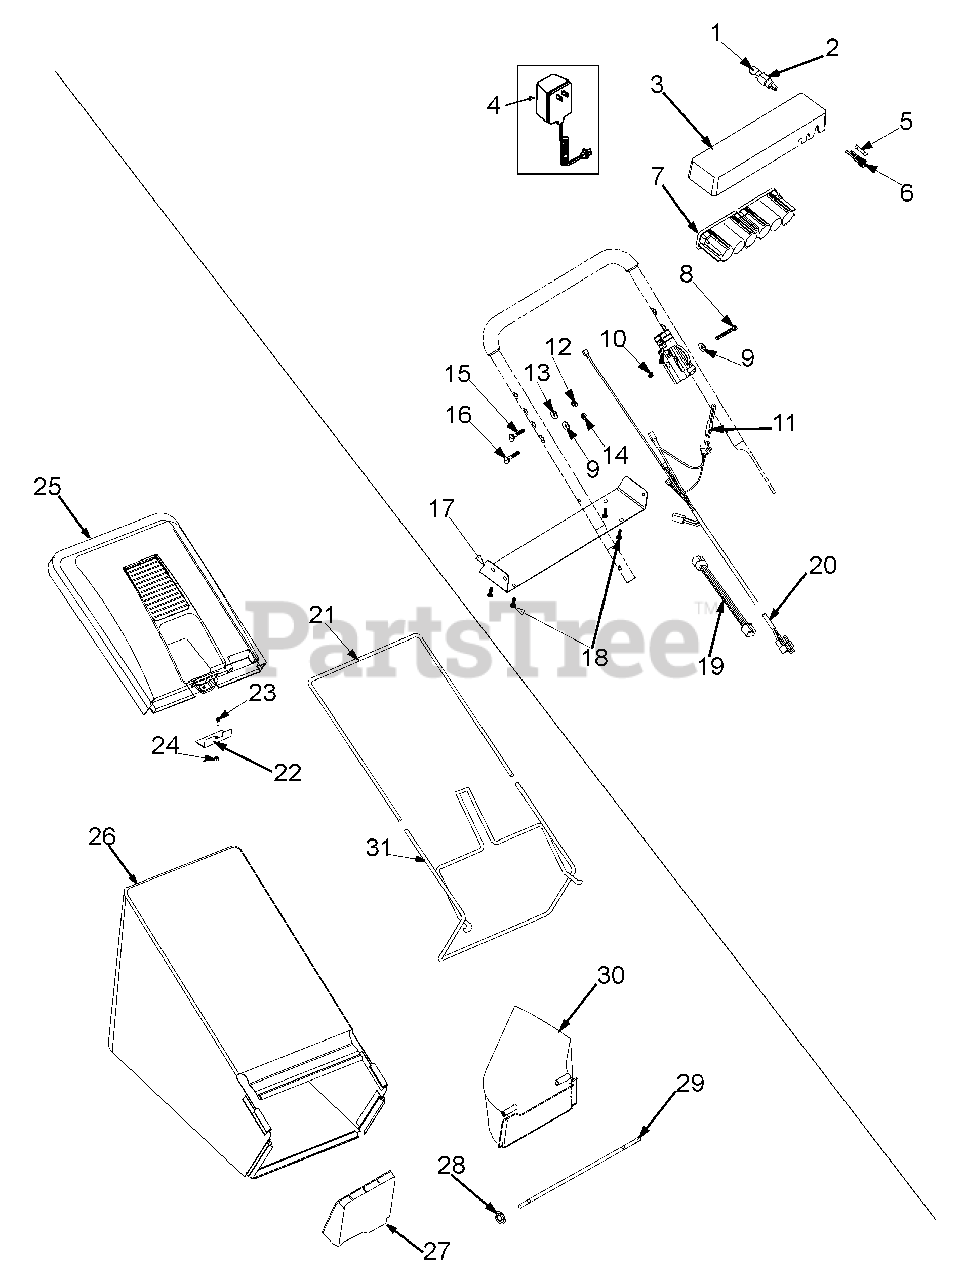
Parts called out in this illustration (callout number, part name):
1	Ignition Key
2	Key Switch
3	Battery Tray
4	Battery Charger
5	Fuse 7.5 Amp
6	Fuse Holder
7	Battery 12V
8	Hex Screw: 1/4-20: 2.0
9	Bell Washer .265 x .75 x .062
10	Special Hex Nut 5/16-18
11	Plug
12	Nut 5/16-18
13	Bell Wash .340 ID x .872 OD
14	Hex Nut 1/4-20
15	Carriage Bolt 5/16-18 x 1
16	Carriage Screw
19	Harness Extension
20	Harness
23	Hex Screw 1/4 -20 x .5
24	Hex Nylon L-Nut 1/4-20
25	Hardtop Cover w/o Logo: Econo: Blk.
26	Grass Bag: Soft Top w/ Logo
28	Nut: Spd. .3125 ID
30	Side Discharge Adapter
